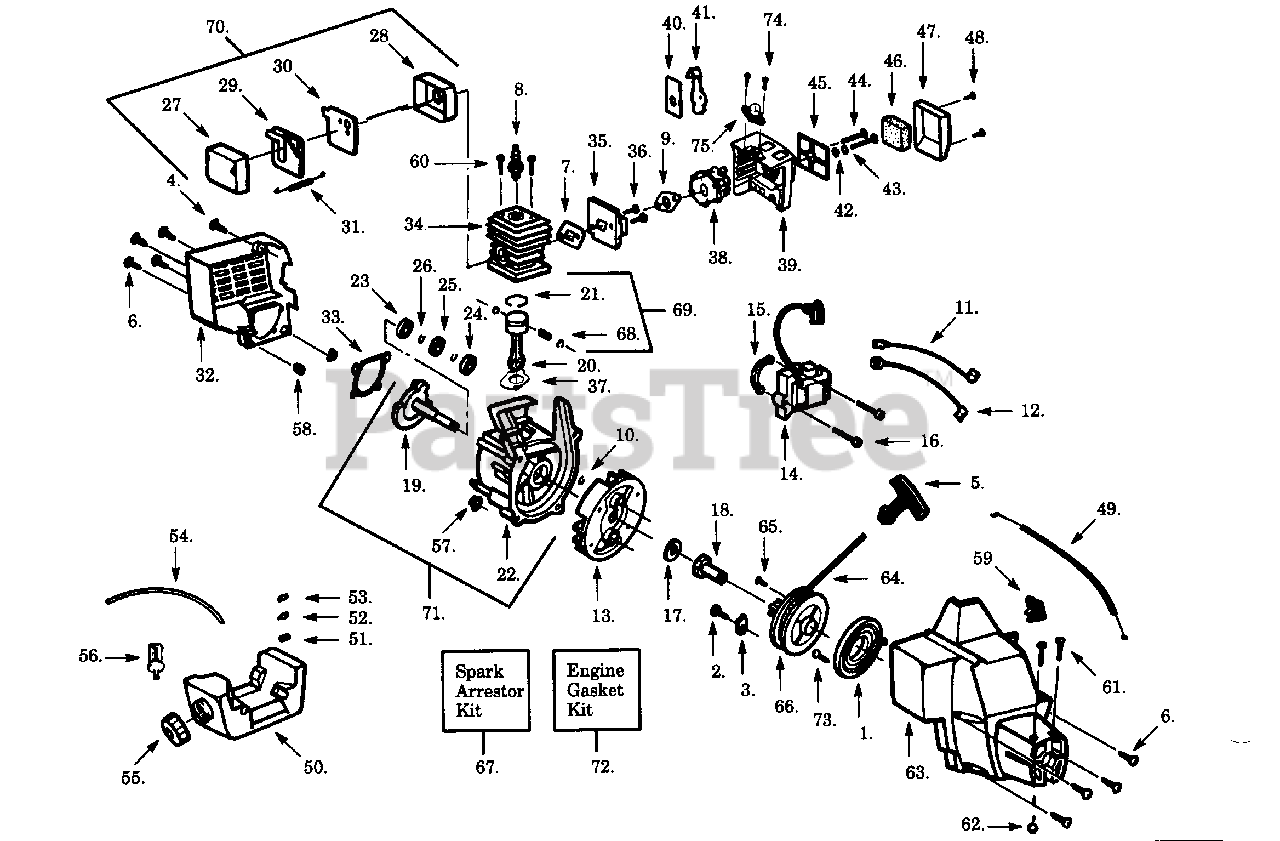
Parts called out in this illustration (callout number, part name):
1	Starter Spring
3	Retainer
5	Starter Handle
6	Screw
7	Cylinder Gasket
8	Spark Plug
10	Retainer
11	Lead Wire
12	Ground Wire
13	Flywheel Ass'y.
14	Ignition Module
18	Drive Coupling
19	Crankshaft Ass'y.
20	Connecting Rod Ass'y.
21	Piston Ring
22	Crankcase Ass'y.
23	Inner Bearing
24	Outer Bearing
25	C'case Seal
26	Retaining Ring
27	Muffler Body
28	Muffler Cover
29	Muffler Baffle-Exit
30	Muffler Baffle-First
31	Muffler Spring
34	Cylinder
37	Gasket
38	Type I (WA-215)
38	Type II (WA-218)
41	Choke Shutter
42	Wave Washer
43	Choke Spacer
49	Throttle Cable Ass'y.
51	Check Valve
53	Retainer
54	Fuel Line
54	Return Line
55	Fuel Cap Ass'y.
56	Fuel Pickup Ass'y.
57	C'case Isolator
58	Shroud Isolator
59	On/Off (Old style)
59	Momentary(New style)
64	Rope Kit
65	Screw
66	Starter Pulley
67	Spark Arrestor Kit
68	Piston Pin Retainer
69	Piston Kit (Inc. 21,68, & Pin)
70	Muffler Kit
71	C'case & C'shaft Assy (Inc. 10,19, 22-26)
72	Engine Gasket Kit (Inc.7,9,33,37)
74	Bulb Ass'y.-Type II
75	Screw-Type II
